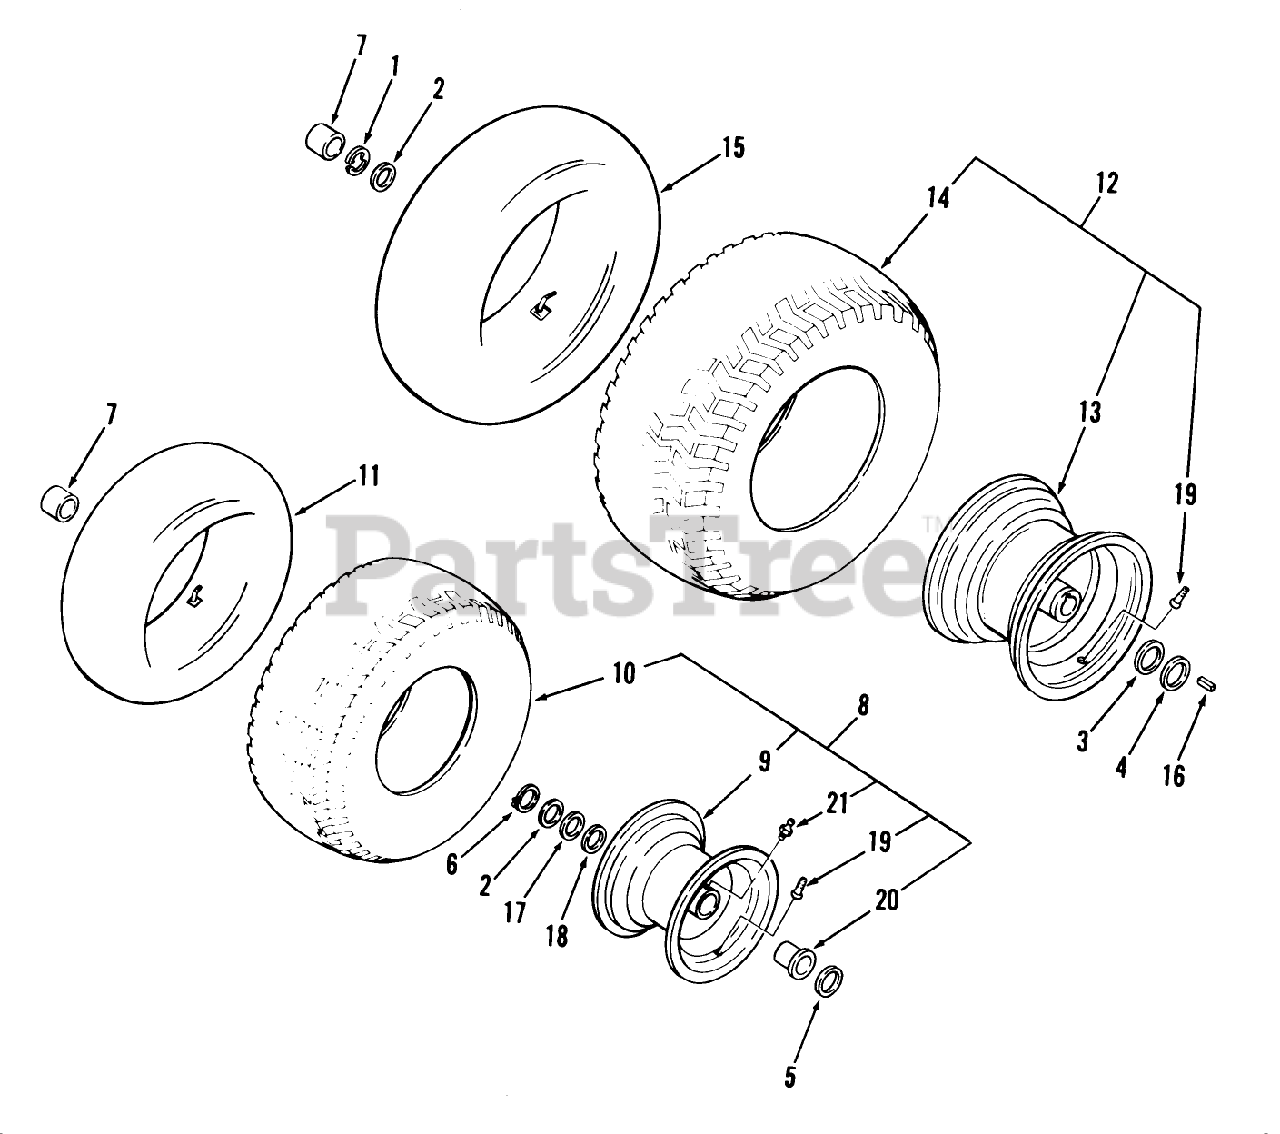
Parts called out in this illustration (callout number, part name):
2	WASHER
3	WASHER-SHIM
4	WASHER
10	TIRE
12	ORDER COMPONENT PARTS
16	SQ KEY
17	WASHER
18	WASHER-SHIM
19	VALVE
20	BUSHING-FLANGED
